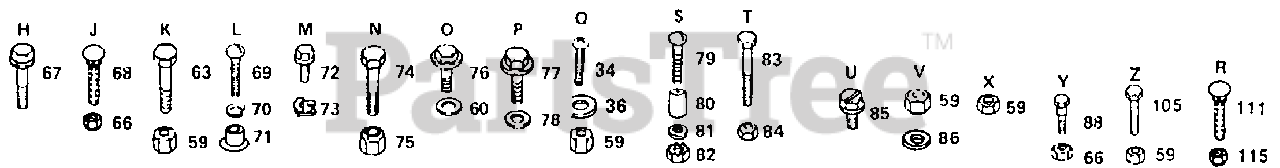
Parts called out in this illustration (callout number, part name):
34	SCREW
36	WASHER
60	WASHER PM
63	BOLT
68	BOLT
69	SCREW
70	LOCKWASHER
71	WELDNUT
73	"""J"" FASTENER LT"
74	BOLT T
76	SCREW
77	SCREW
78	WASHER
79	SCREW
80	SPACER LT
81	WASHER
83	BOLT
84	NUT GTV
85	SCREW LT
86	WASHER
111	BOLT
115	"NUT,KEPS"
